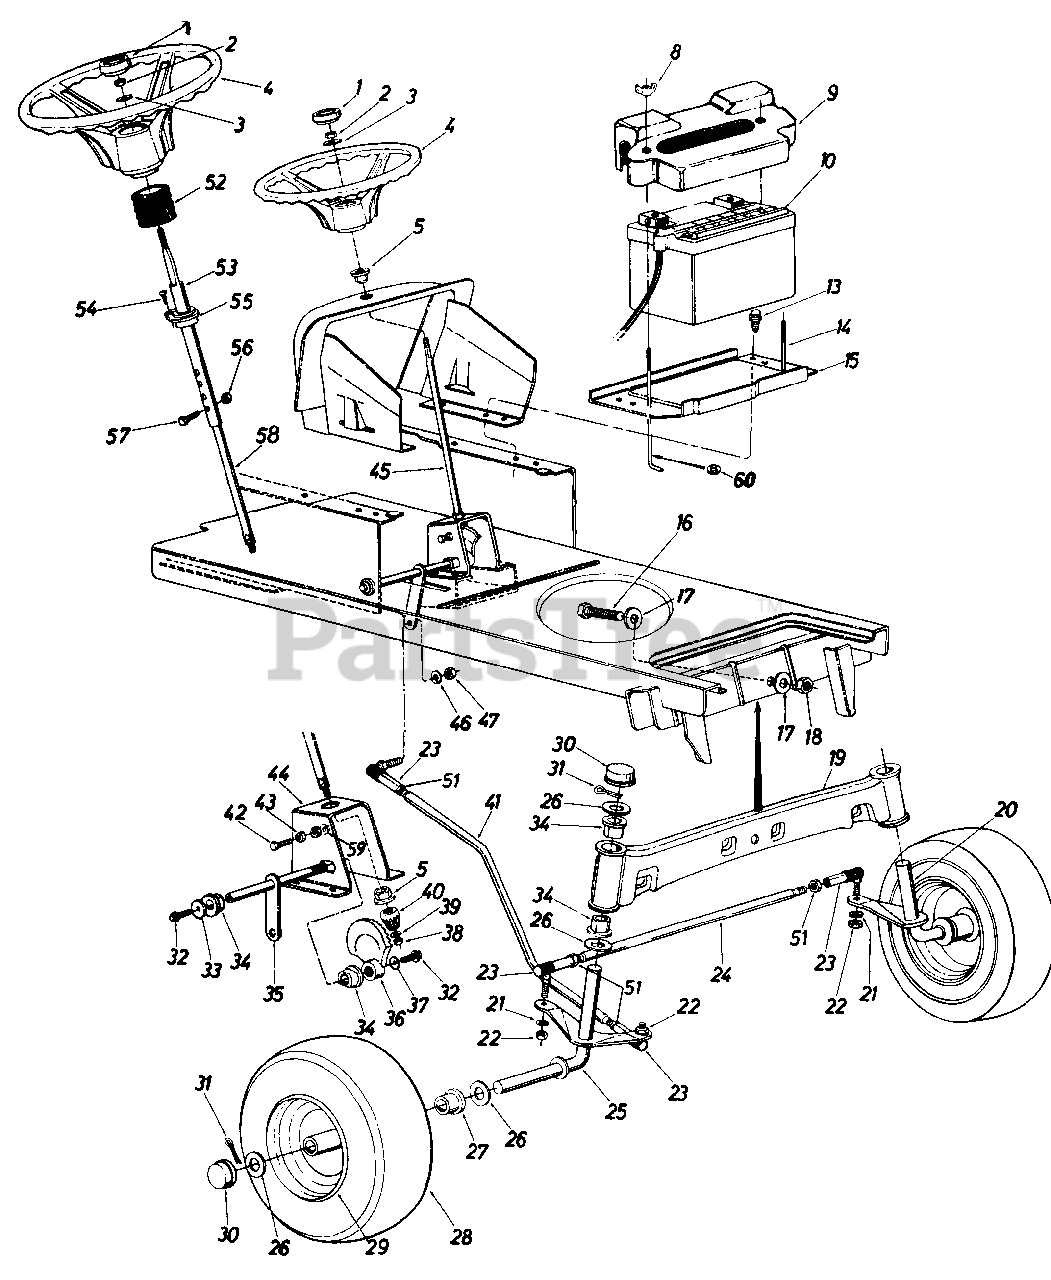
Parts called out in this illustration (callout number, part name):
1	Steering Wheel Cap
2	Hex Cent. L-Nut 5/16-24 Thd.
3	Bell-Wash. 5/16" I.D. x .87" O.D. x .060
4	N Steering Wheel
5	Plastic Hex Bearing 5/8" I.D.
8	Wing Nut Plastic 1/4-20 Thd.
9	N Battery Cover
10	N 12-V Battery
13	Hex Thd. Rolling Scr. 1/4-20x.50" Lg.
14	Battery Hold Down Rod
16	Hex Scr. 5/8-18 x 2.50" Lg.
17	Flat Wash. .66" I.D. x 2.25" O.D. x .17
18	Hex Cent. L-Nut 5/8-18 Thd.
19	Front Pivot Bar Ass'y.
20	Front Axle Ass'y. L.H.
21	L-Wash. 818" I.D.
22	Hex Nut 3/8-24 Thd.
23	Ball Joint Ass'y.
24	Tie Rod
25	Front Axle Ass'y. R.H.
26	Fl-Wash. .780 I.D. x 1.59 O.D.
27	Flange Bearing
28	Front Wheel Ass'y. Comp.
29	Front Wheel Rim Only
30	N Dust Cover
31	Cotter Pin 5/32" Dia. x 1.00" Lg.*
32	Hex Scr. 3/8-24 x 75" Lg.Grade 5
33	Fl-Wash. 3/8 I.D. x 1.25 O.D. x .090
34	Flange Double "D" Brg. .753I.D.
35	Steering Arm Shaft Ass'y.
36	Side Gear Steering
37	Bell-Wash. 3/8" I.D.
38	Hex Cent. L-Nut 5/16-24 Thd.
39	Fl-Wash. 5/16" I.D. x .62 O.D. x .059
40	Pinion Gear Steering
41	Drag Link
42	Hex Cap Scr. 3/8-16 x 1.25n Lg.
43	Hex Nut 3/8-16 Thd.
44	Steering Gear Sup. Ass'y.
45	Steering Shaft
46	L-Wash. 3/8" I.D.
47	Hex Nut 3/8-24 Thd.
51	Hex Jam Nut 3/8-24 Thd.
52	Steering Bellow
53	Upper Steering Shaft
54	Oval Hd. Cr.-Sunk Scr. #10 x 5/8" Lg.
55	Fl-Bearing .89" I.D. x 1.36" O.D.
56	Hex L-Nut 1/4-20 Thd.
57	Hex Bolt 1/4-20 x 1.31 Lg.
58	Lower Steering Shaft
59	Nylon Cap
60	Push Nut
